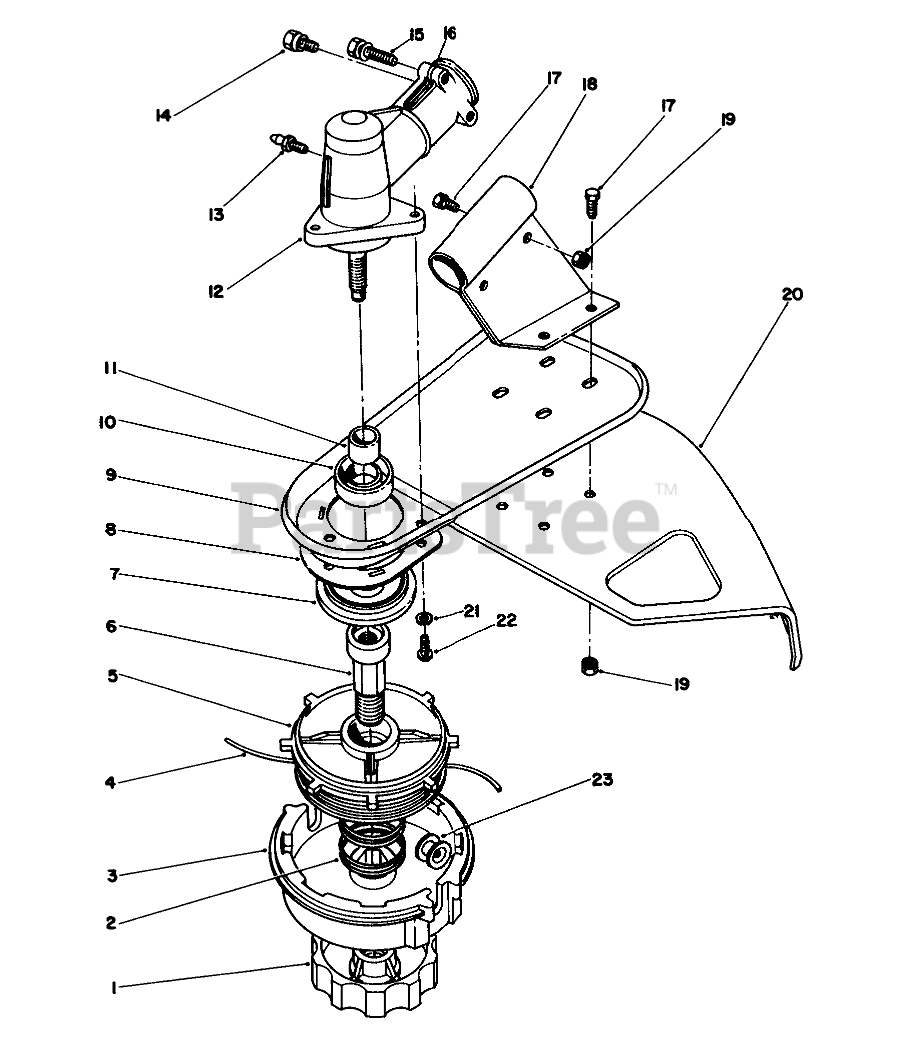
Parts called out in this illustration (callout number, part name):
1	LH KNOB(SERVICE ONLY)
2	SPRING (SERVICE)
3	SPOOL HSG (SERVICE ONLY
4	REPL LINE PKG
5	INNER SPOOL(SERV ONLY)
6	SHAFT (SERVICE ONLY)
7	DUST CAP F/W
8	GRASS WRAP GUARD
9	SHIELD SUPPORT R
10	OIL SEAL
11	SPLINED SLEEVE
12	Gear Box Assembly (Incl. Ref. #10, 11, & 13-15)
14	HHMS SCREW
15	HHMS SCREW
16	WASHER
17	SCREW-SHH
18	SHIELD BRKT
19	NUT-LOCK, NI
20	GRASS SHIELD R
21	LOCKWASHER
22	SCREW
23	EYELET(SERVICE)
